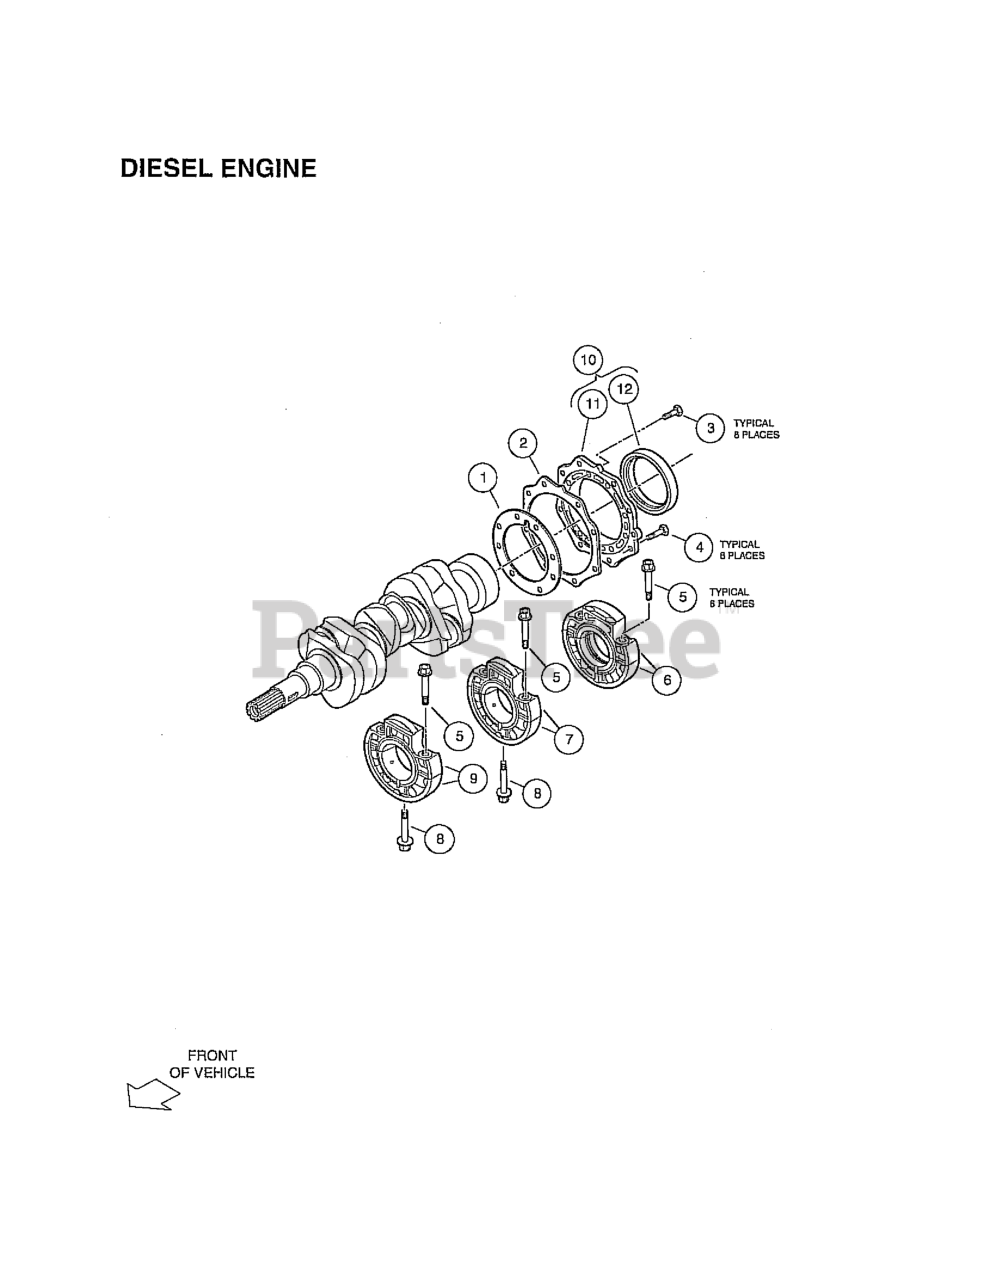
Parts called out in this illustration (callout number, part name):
1	GASKET, BEARING CASE
2	GASKET, COVER
3	BOLT, M6 X 1 X 20
4	BOLT, M6 X 1 X 22
5	BOLT, BEARING CASE, TOP
6	ASSY CASE, MAIN BRG, FIRST
7	ASSY CASE, MAIN BRG, SEC
8	BOLT, BEARING CASE, BOTTOM
9	ASSY CASE, MAIN BRG, THIRD
10	ASSY, COVER, BEARING CASE
11	COVER, BEARING CASE
